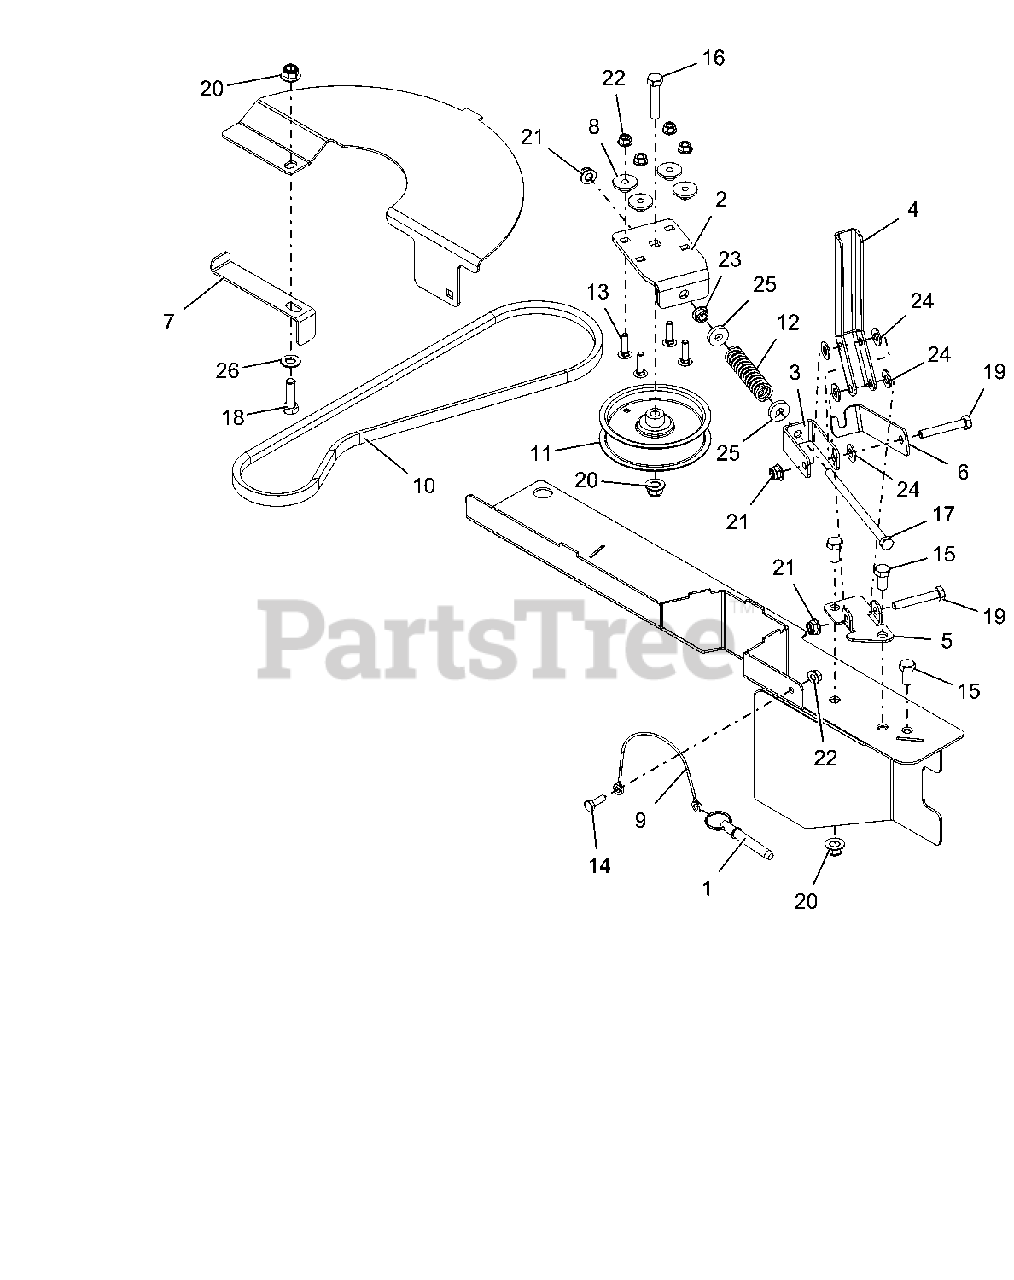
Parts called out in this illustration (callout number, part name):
1	PIN, SPRING BALL .375OD X 1.50
2	BRACKET, ADJUSTABLE IDLER
3	LINK - IDLER RELEASE
4	LEVER - IDLER RELEASE
5	MOUNT - IDLER RELEASE LEVER
6	LOCK - IDLER RELEASE LEVER
7	FINGER - BELT
8	BSHG-FLG .265X.477X.375X1.00
9	CABLE, 12.0 LANYARD, NYLON
10	V-BELT, 4L WRAPPED CLUTCHING
11	PULLEY, IDLER 4.00
12	SG-COMP .092X.77X3.13 WLD 36
13	@BLT-RDHDSQNK .25-20X1.00 G5YZ
14	@BLT-HEX .25-20X.75 GR5 YWZC
15	@BLT-HEX .38-16X.75 GR5 YWZC
16	@BLT-HEX .38-16X1.75 GR5 YWZC
17	@BLT-HEX .31-18X5.50 GR5 YWZC
18	@BLT-HEX .38-16X1.25 GR5 YWZC
19	@BLT-HEX .31-18X2.00 GR5 YWZC
20	@NUT-LK-NYL-FLG .38-16 YWZC
21	@NUT-LK-NYL-FLG .31-18 YWZC
22	@NUT-LK-TOP-FLG .25-20 YWZC
23	@NUT-SPNLK-FLG .312-18 YWZC
24	WSHR-FL-NY .375X.75X.060
25	WSHR-FL-STL .328X.87X.179 YWZC
26	@WSHR-FL-STL.406X.812X.065 YWZ
